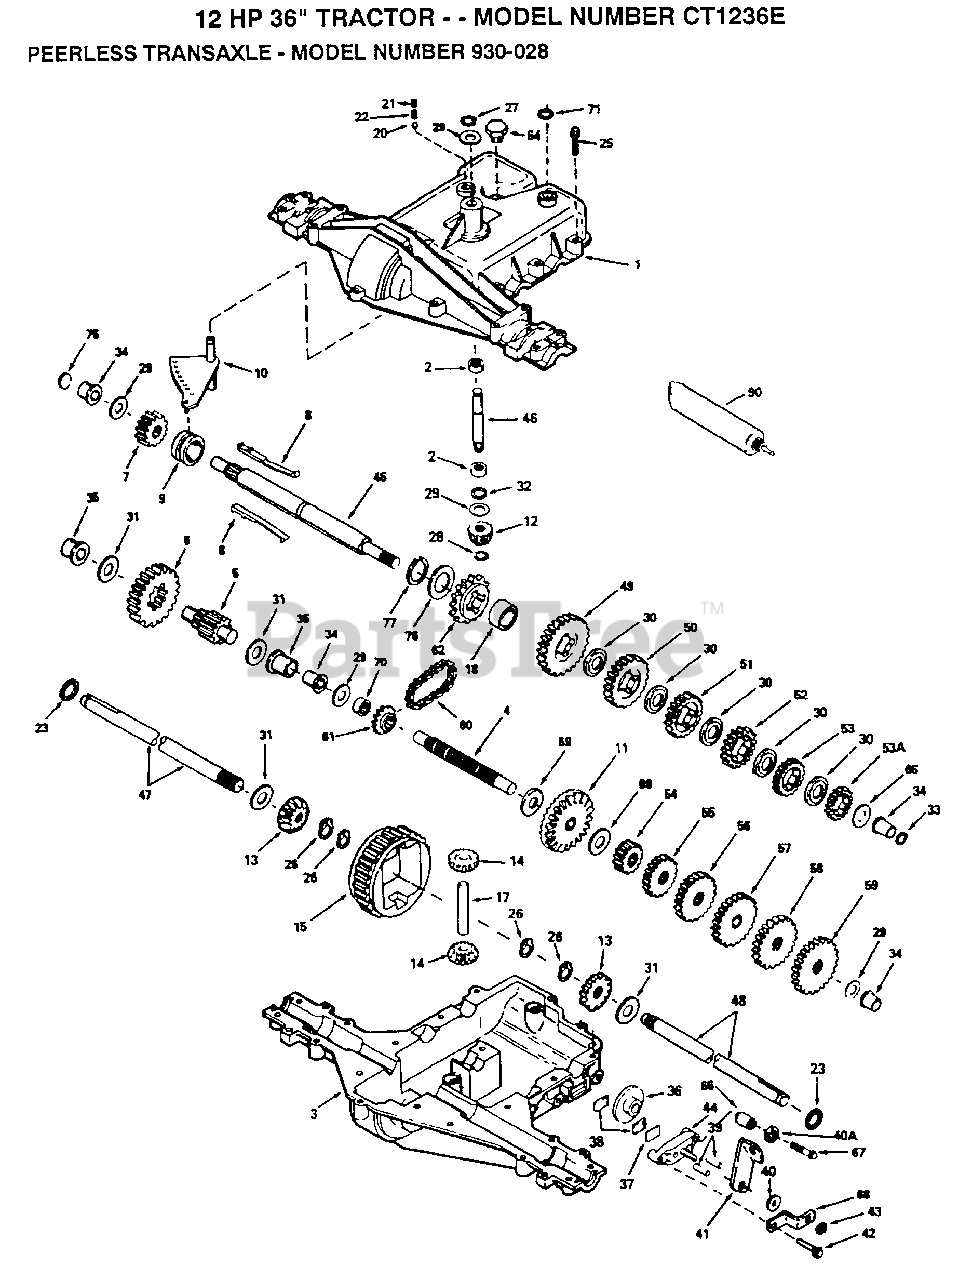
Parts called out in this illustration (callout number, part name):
1	COVER, TRANSAXLE
2	BEARING, NEEDLE
3	CASE, TRANSAXLE
4	SHAFT, COUNTER
5	SHAFT, PINION ASSEMBLY, OUTPUT
6	GEAR, OUTPUT
7	GEAR, SPUR, 15 TEETH
9	COLLAR, SHIFTER
10	ROD & FORK ASSY, SHIFT
11	GEAR, BEVEL, 42 TEETH
12	BEVEL PINION, INPUT
13	GEAR, BEVEL
14	GEAR, BEVEL, PINION
18	SPACER, NEUTRAL
20	BALL STEEL, 5/16" DIA.
21	SCREW, 3/8-16 X 3/8"
25	SCREW, 1/4-20 X 1-1/4
26	RING RETAINER
27	RING, RETAINER
28	RETAINING RING
29	WASHER THRUST
30	WASHER THRUST
33	SEAL, SQUARE CUT
34	BUSHING, FLANGED
35	BUSHING, FLANGED
36	DISK, BRAKE
37	PLATE BRAKE PAD
40	WASHER, FLAT
40A	WASHER FLAT
41	LEVER BRAKE
42	SCREW, 1/4-20 X 1-1/4
43	LOCKNUT 5/16-24
44	HOLDER BRAKE PAD
45	SHAFT, BRAKE, 4 KEYED
46	SHAFT, INPUT
49	GEAR, SPUR, 37 TEETH
50	GEAR, SPUR, 35 TEETH
51	GEAR, SPUR, 30 TEETH
52	GEAR, SPUR, 25 TEETH
53	GEAR, SPUR, 22 TEETH
53A	GEAR, SPUR, 19 TEETH
54	GEAR, SPUR, 12 TEETH
55	GEAR, SPUR, 15 TEETH
56	GEAR, SPUR, 20 TEETH
57	GEAR, SPUR, 25 TEETH
58	GEAR, SPUR, 28 TEETH
59	GEAR, SPUR, 31 TEETH
60	CHAIN, ROLLER
61	SPROCKET 9T
62	SPROCKET 18T (REV)
64	PLUG, THRDED, 9/16-18
65	WASHER, THRUST
67	SCREW FLNG HEX 1/4-20 X 2-1/4
68	BRKT BRAKE LEVER
69	WASHER THRUST
71	SEAL SQUARE CUT
76	WASHER, THRUST
77	RING, RETAINING
90	GREASE BENTONITE, 32 OZ.
